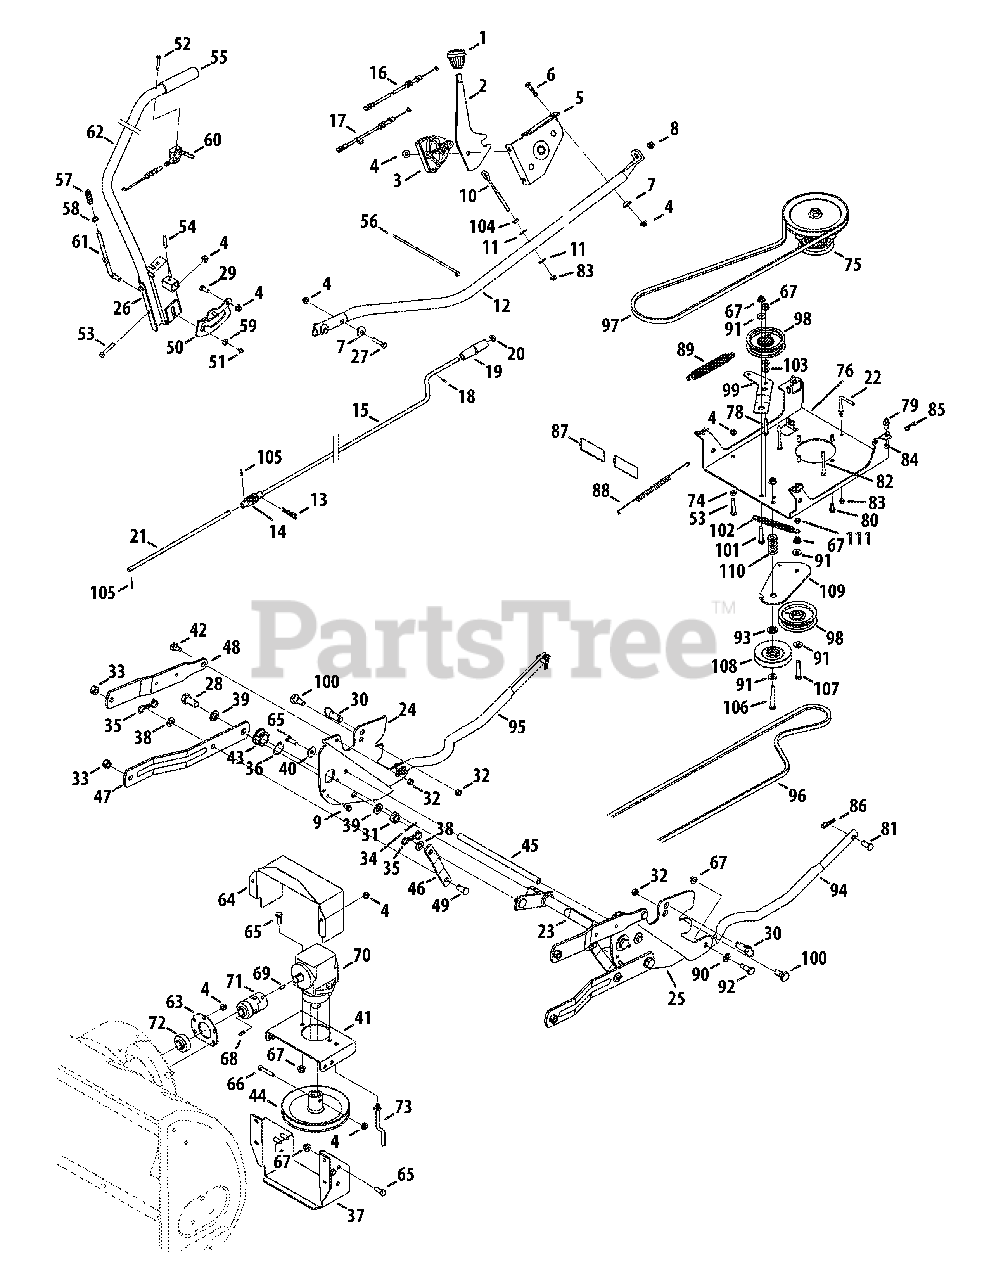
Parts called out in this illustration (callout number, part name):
2	Chute Tilt Handle
3	Chute Tilt Cable Guide
4	Nylon Hex Lock Nut, 5/16-18
5	Chute Tilt Bracket Assembly
6	Carriage Bolt, 5/16-18 x 1.5
7	Saddle Washer, .32 x .93
8	Plastic Bushing
9	Self Tapping Screw
10	Eye Bolt
11	Bell Washer, .265 x .75
13	Cotter Pin, .08 x 1.42
14	Joint Block Assembly
15	Chute Crank Rod, .38 x 35
16	Chute Cable, 62"
17	Chute Cable w/ Clip, 62"
18	Rolled Pin, 1/8 x .63
19	Crank Knob
20	Push Cap, 3/8 ID
21	Rod, .375 x 13.50
22	Belt keeper Pin
23	Rod Assembly
24	RH Support Plate Assembly
25	LH Support Plate Assembly
26	Lift Bracket Assembly
27	Hex Cap Screw, 5/16-18 x 1.50
28	Hex Cap Screw, 5/8-18 x 1.31
29	Hex Cap Screw, 5/16-18 x .75
30	Quick Release Pin
31	Slotted Hex Nut, 5/8-18
32	Hex Lock Nut, 3/8-16
33	Hex Lock Nut, 1/2-13
34	Cotter Pin, 1/8 x 1.25
35	Cotter Pin, Bow Tie
36	Snap Ring
37	Skid Plate
38	Flat Washer, .51 x 1.0 x .060
39	Flat Washer, .64 x 1.12 x .125
40	Bell Washer, .396 x 1.14 x .095
41	Drive Mounting Bracket
42	Shoulder Screw, .5 x .29, 3/8-16
43	Flange Bearing w/ Flats
44	Drive Pulley, 7"
45	Rod, 1/2 x 11.55
48	Link, 13.25
49	Clevis Pin, .50 x .78
50	Snow Thrower Lift Bracket
51	Hex Index Washer Screw #10-24
52	Pan Phillips Screw, #10-24 x .75
53	Hex Cap Screw, 5/16-18 x 1.75
54	Heavy Duty Spirol Pin, 1/4 x 1.5
55	Handle Grip
56	Cable Tie
57	Compression Spring
58	Flat Washer, .385 x .62 x .063
59	Flat Washer, .194 x .62 x .063
60	Lift Cable, 42" w/ Trigger Control
61	Lift Index Rod
62	Lift Handle Tube
63	Bearing Housing, 1.85 ID
64	Belt Cover
65	Hex Cap Screw, 3/8-16 x 1.0
66	Socket Head Cap Screw
67	Flange Lock Nut, 3/8-16
68	Square Key, 3/16 x .75
69	Hi-pro Key, 3/16 x .75
70	Right Angle Drive
71	Coupling
72	Flange Ball Bearing, .75 x 1.85
73	Belt Keeper Rod
74	Flange Nut, 5/16
75	Spindle Assembly
76	Pulley Mounting Bracket
78	Hex Cap Screw, 3/8-16 x 1.75
79	Pin 5/16-18
80	Carriage Bolt, 5/16-18 x .62
81	Clevis Pin, .5 x 1.18
82	Belt Keeper Pin
83	Nylon Hex Lock Nut, 1/4-20
84	Hex Lock Nut, 5/16-18
85	Click Pin, .092 x 1.64
86	Internal Cotter Pin, .125 x 1.75
87	Reflector
88	Extension Spring .50 x 12.00
89	Extension Spring .91 x 7.33
90	Flat Washer, .531 x .93 x .09
91	Flat Washer, .38 x .93 x .11
92	Shoulder Screw, 3/8-16
93	Shoulder Spacer, .625 x .169
94	LH Support Tube
95	RH Support Tube
96	V-Belt
97	V-Belt
98	Idler Pulley 3.50 dia.
99	Idler Bracket
100	Shoulder Bolt
101	Hex Cap Screw, 3/8-16 x 1.25
102	Extension Spring, .620 x 5.62
103	Flat Washer, .407 x .812 x .135
104	Hex Lock Nut, 1/4-20
105	Spirol Pin, .156 x .875
106	Hex Cap Screw, 3/8-16 x 2.75
107	Hex Cap Screw, 3/8-16 x 2.00
108	Idler pulley, 4" Diameter
109	Idler Pivot Arm
110	Spacer
111	Nut, 3/8-16, Jamlock
